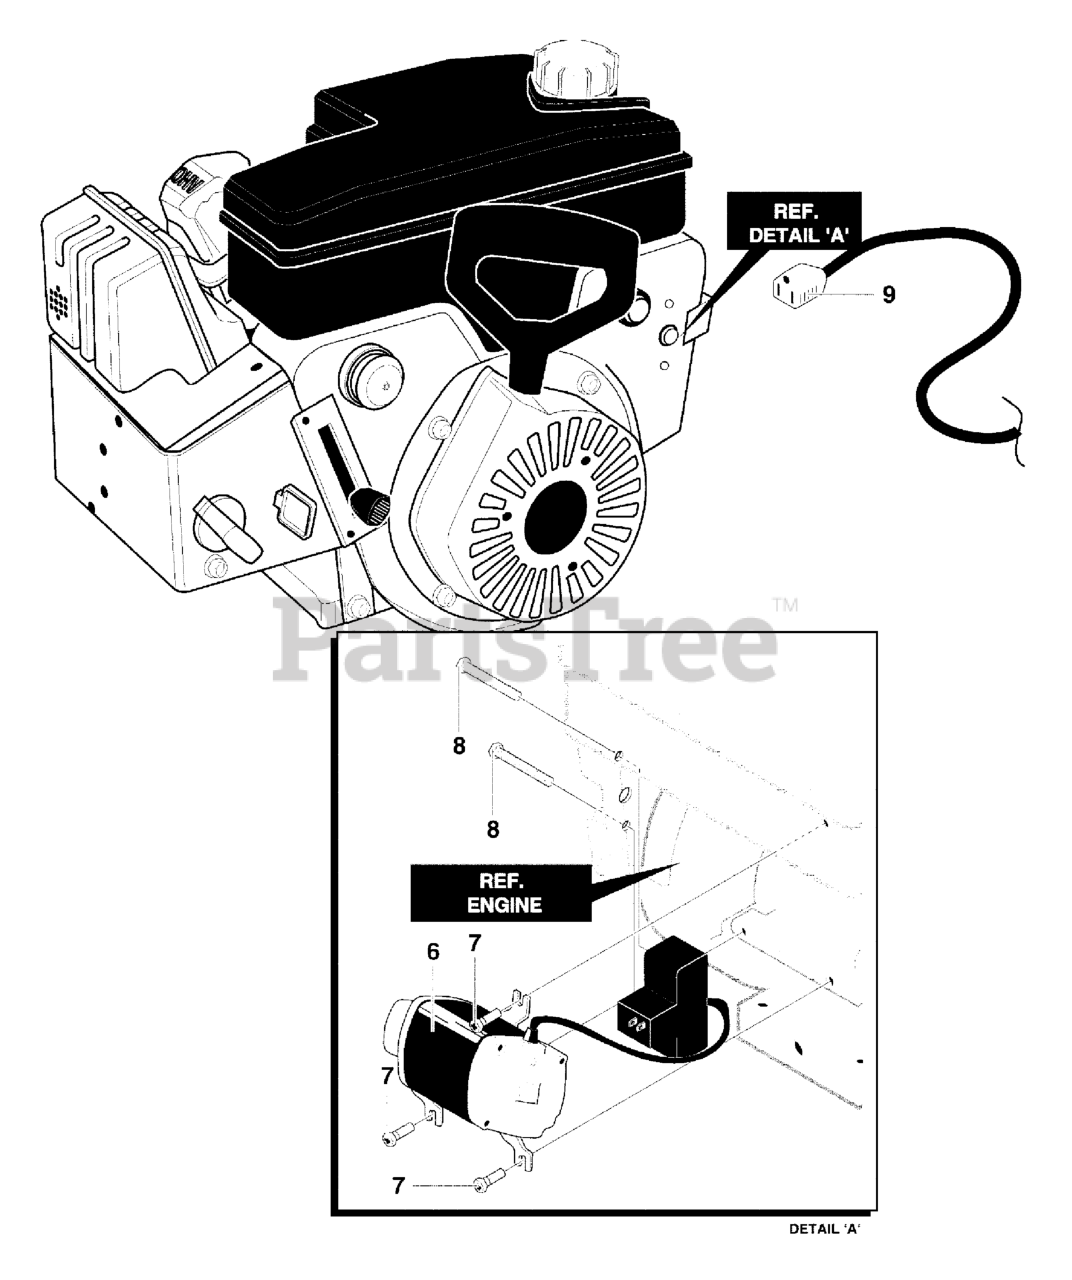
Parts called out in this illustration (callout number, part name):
6	MOTOR, STARTER
7	SCREW, 1/4-20X .50
8	SCREW, #6-32X2.50
9	CORD, Electric, 10FT. 110V
